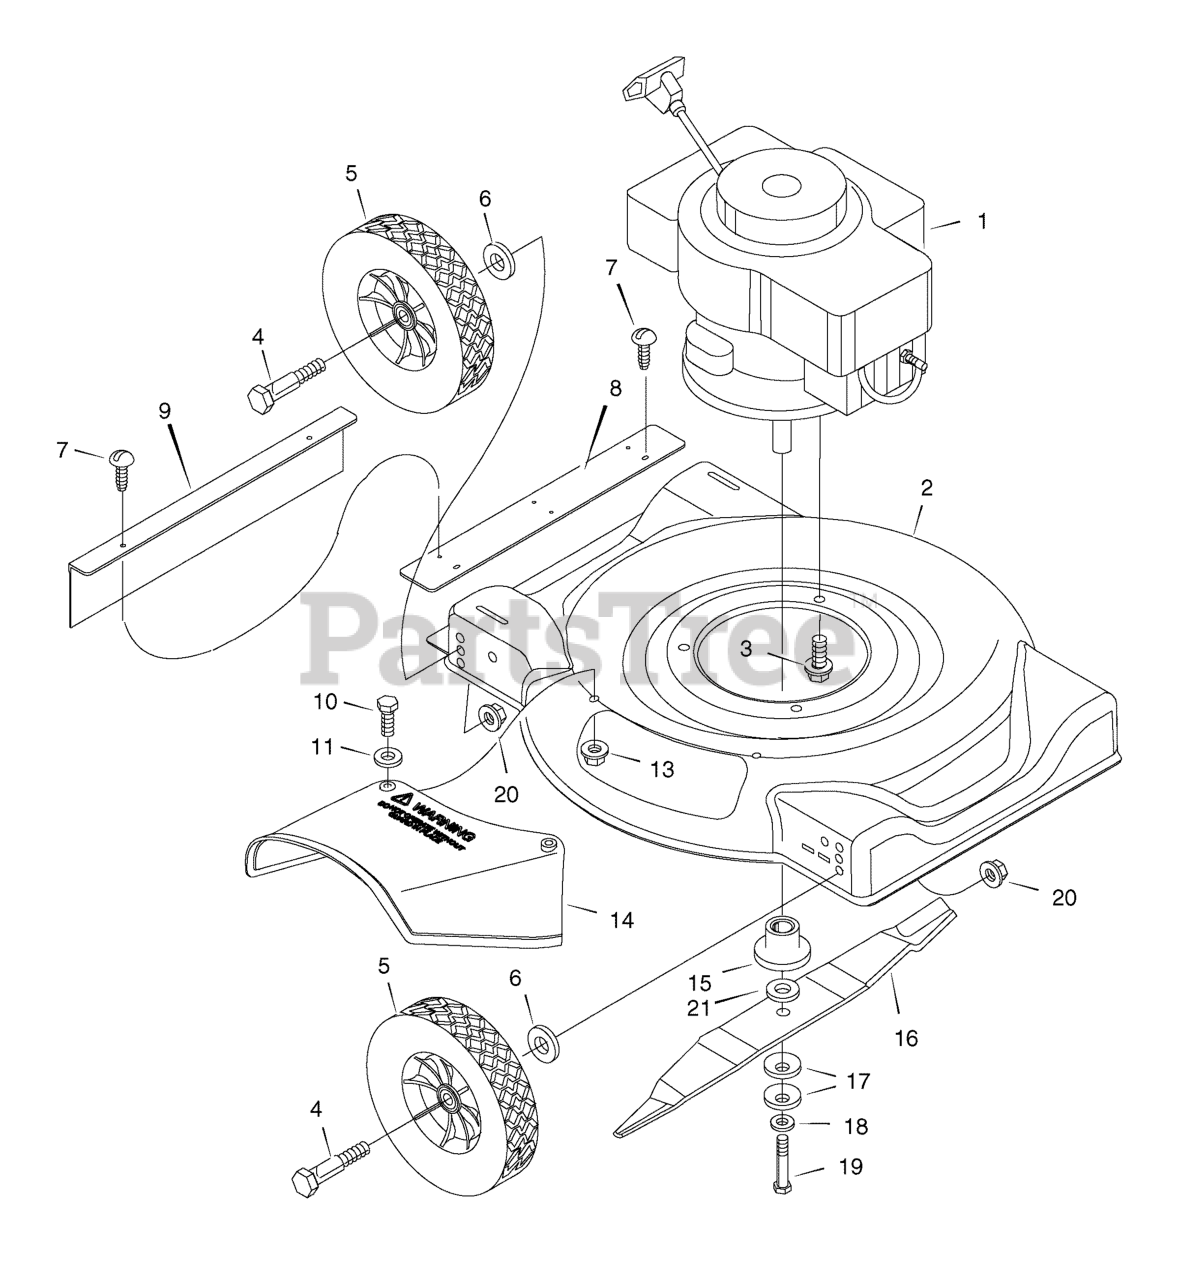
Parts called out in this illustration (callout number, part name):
1	ENGINE *
3	BOLT, Engine
4	BOLT, Axle
5	WHEEL & TIRE ASSEMBLY
6	WASHER
8	EXTENSION, Rear
9	DEFLECTOR, Rear
10	BOLT
11	WASHER
13	LOCKNUT
14	DEFLECTOR, Chute
15	BLADE ADAPTER
16	BLADE, 20"
17	WASHER, Blade
20	LOCKNUT
